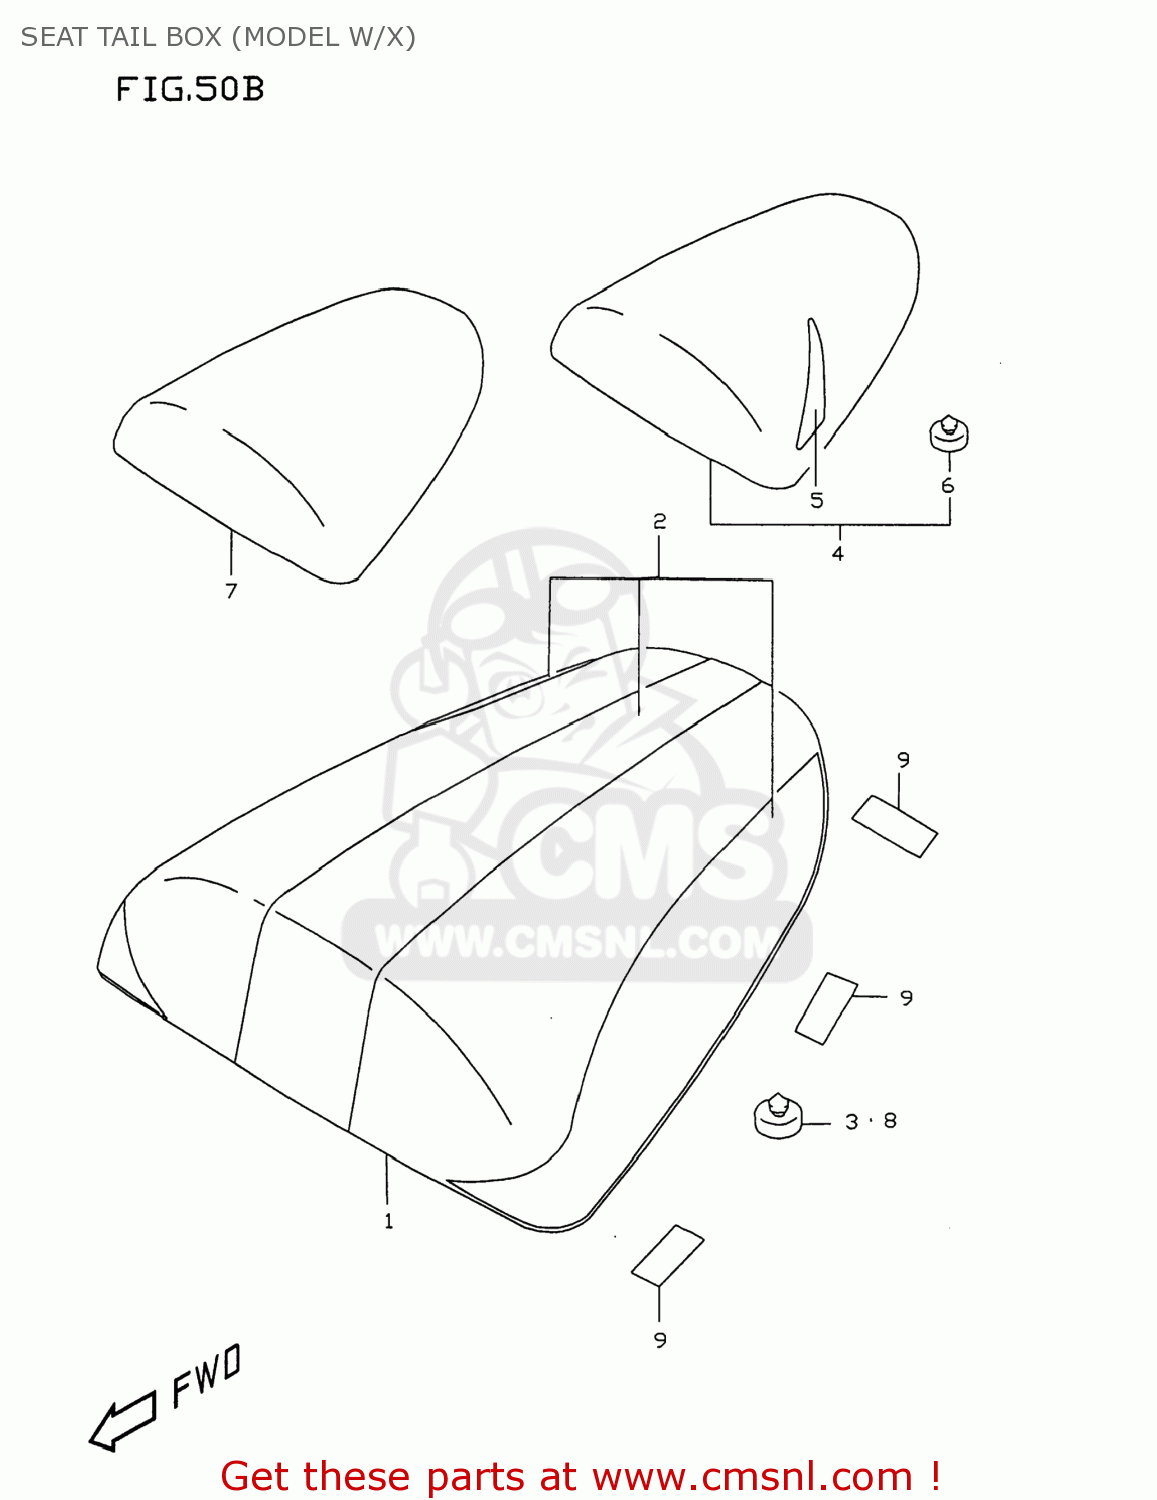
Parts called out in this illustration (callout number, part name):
1	BOX ASSY,SEAT TAIL(BLUE)
2	TAPE SET,BOX SEAT TAIL(WHITE)
3	CUSHION(11.5X22X20)
4	BOX ASSY,SEAT TAIL(WHITE)
5	TAPE SET,BOX SEAT TAIL
6	CUSHION(11.5X22X20)
7	BOX,SEAT TAIL(BLACK)
8	CUSHION(11.5X22X20)
9	PROTECTOR SET,SEAT TAIL BOX
